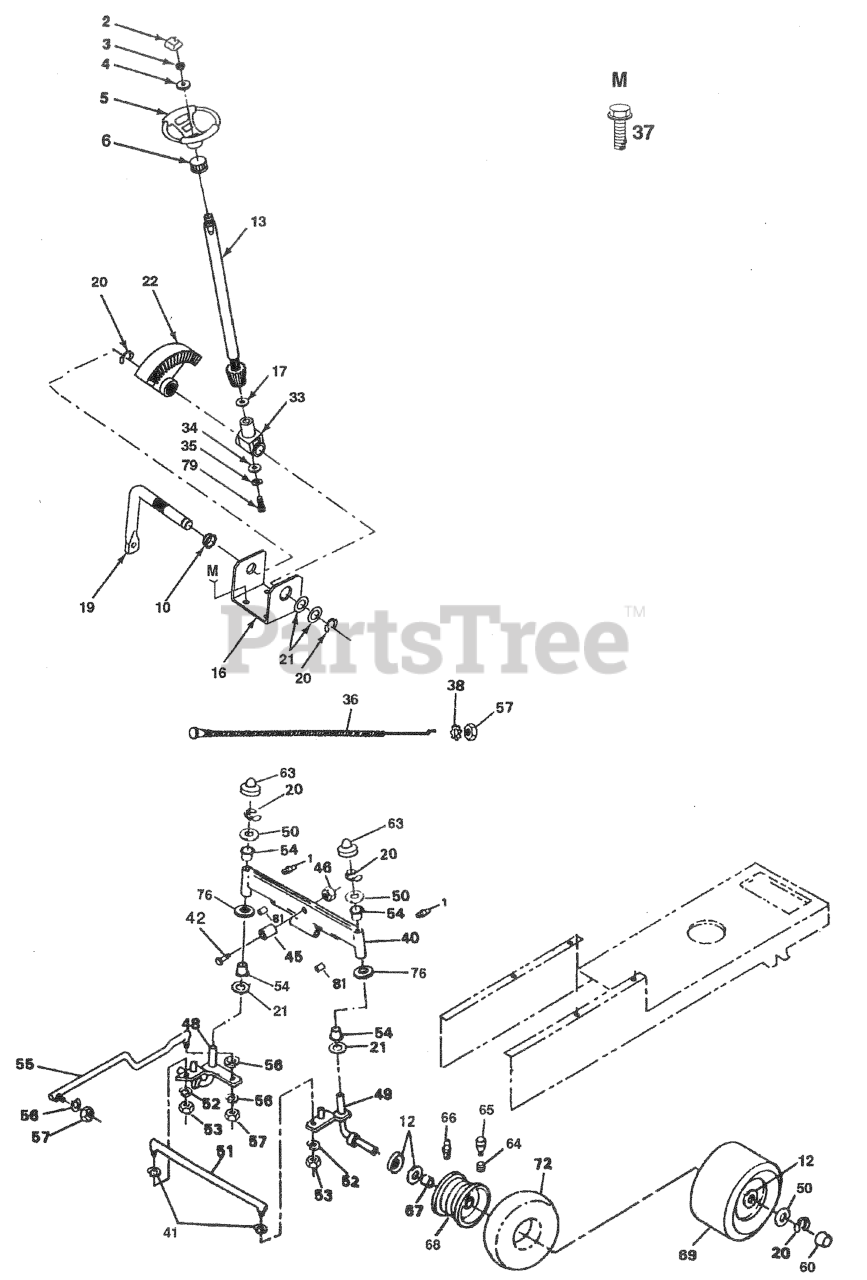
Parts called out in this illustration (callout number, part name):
1	Fitting, Grease
2	Insert, Wheel, Steering
3	lockout, Top 1/2-20 UNF
5	Wheel, Steering
6	Adapter, Wheel, Steering
10	Nyliner, Snap In
12	Washer 25/32 x 1-1/4 x 16 Gauge
13	Shaft, Steering
16	Bracket, Steering
17	Washer, Thrust
19	Shaft, Pitman
20	Ring, Klip
21	Bearing, Thrust
22	Gear, Sector
33	Support, Shaft
34	Washer, Shim 1/4 x 5/8 x .062
35	Washer, Lock Hvy. Helical 1/4
36	Control, Choke
37	Screw, Hex Wsh. Thd. Roll. 3/8-16 x 3/4
38	Washer, Lock, Int/Ext. Tooth 3/8
40	Axle, Front
41	Washer 11/32 x 3/4 x 16 Gauge
42	Bolt 5/8-11 x 3-1/2
45	Bearing, Spacer, Axle, Front
46	Locknut, Hex with Washer Insert 5/8-16
48	Spindle, LH
49	Spindle, RH
50	Washer 25/32 x 1-5/8 x 16 Gauge
51	Rod, Tie
52	Washer, Lock, Heavy Helical Spring
53	Nut, Hex, Nylon 5/16-24 UNF
54	Bearing
55	Link, Drag
56	Washer, Lock 3/8
57	Nut, Hex 3/8-24
60	Cap, Axle, Front
63	Cap, Spindle
64	Cap, Valve
65	Stem, Valve
67	Bearing
69	Tire, Front
72	Tube, Tire, Front
76	Washer 27/32 x 1-1/4 x 16 Gauge
79	Screw, Socket Hex 1/4-20 x 5/8
81	Pin, Axle
86	Fitting, Grease
